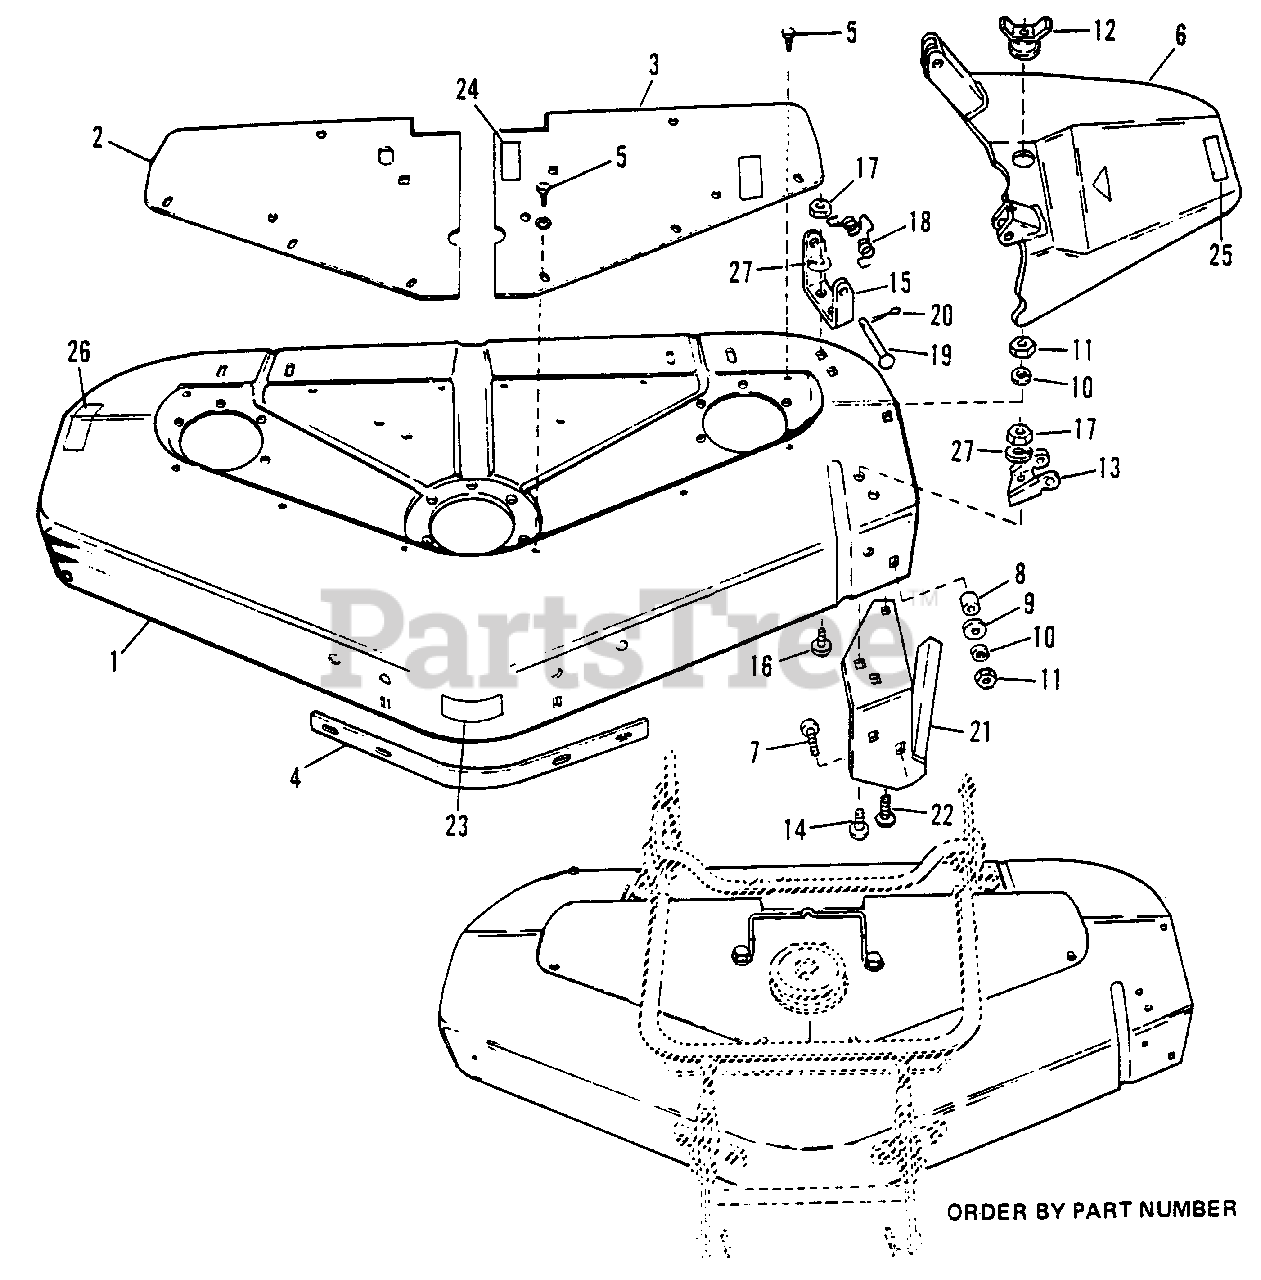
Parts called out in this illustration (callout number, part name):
1	Mower Housing
2	Cover, Right Hand
3	Cover, Left Hand
4	Reinforcing Bar
5	Taptite Screw, 1/4"-20 x 3/8"
6	Deflector
7	Carriage Bolt, 3/8"-16 x 1-1/4"
9	Special Washer
10	Lockwasher, 3/8"
11	Full Hex Nut, 3/8"-16
12	Nut Assembly
13	Front Half Hinge
14	Carriage Bolt, 5/16"-18 x 1"
15	Rear Half Hinge
16	Carriage Bolt, 5/16"-18 x 3/4"
17	Full Hex Nut, 5/16"-18
20	Cotter Pin, 1/8" x 3/4"
21	Stone Guard Assembly
22	Carriage Bolt, 3/8"-16 x 1"
23	Film, Simplicity
24	Film, Belt Installation
25	Decal, Danger
26	Decal, Caution
27	Lockwasher, 5/16"
